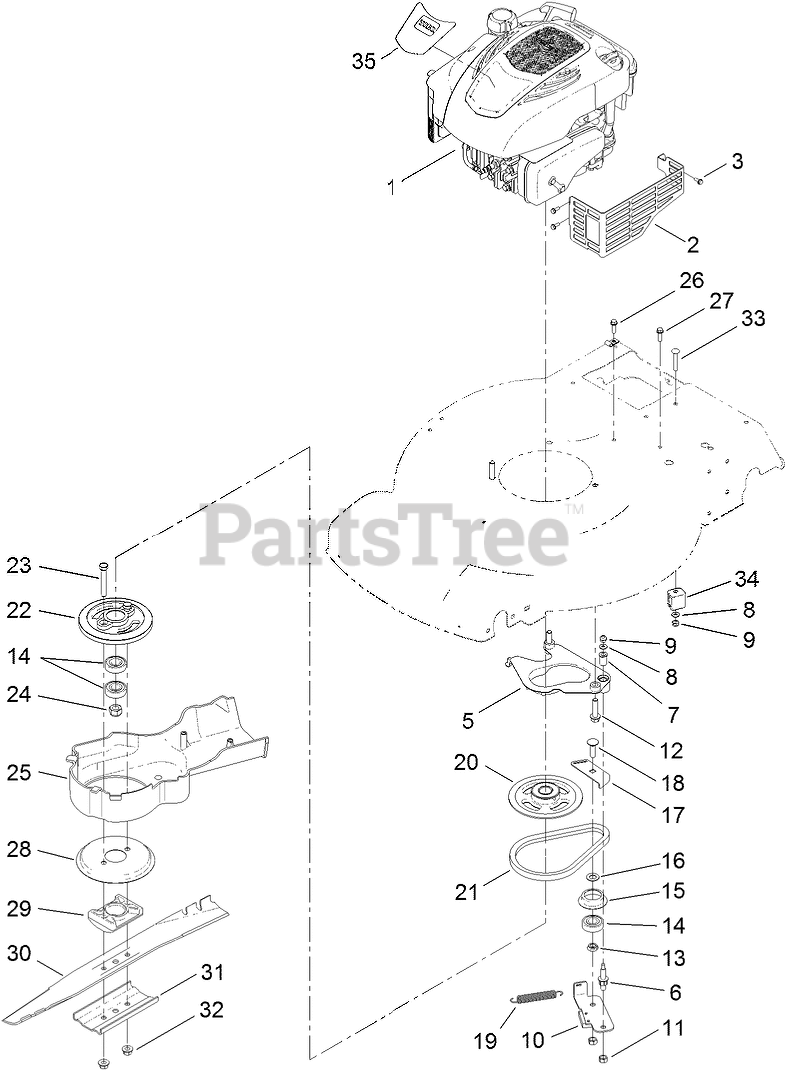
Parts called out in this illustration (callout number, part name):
2	SHIELD-MUFFLER
3	SCREW-TAPTITE
5	PLATE-ANCHOR
6	BOLT-SHOULDER
7	BUSHING
8	WASHER-FLAT
9	NUT-LOCK, NI
10	BRAKE ARM ASM
12	SCREW-HWH
13	SPACER-BEARING
14	BEARING-BALL
15	RETAINER-BELT
16	WASHER-PLAIN
17	PLATE-GUIDE
18	BOLT-CARR
19	SPRING-TENSION, BRAKE
20	PULLEY
21	BELT
22	DRUM
23	SCREW-HH
24	NUT-HEX
26	CLIP-CLOSED, INSULATED
27	SCREW-HWH
28	DISC
29	SUPPORT-BLADE
30	BLADE
31	SUPPORT-BLADE
32	NUT-LOCK
33	SCREW-CARR
34	ANCHOR-CABLE
35	DECAL-SHROUD
